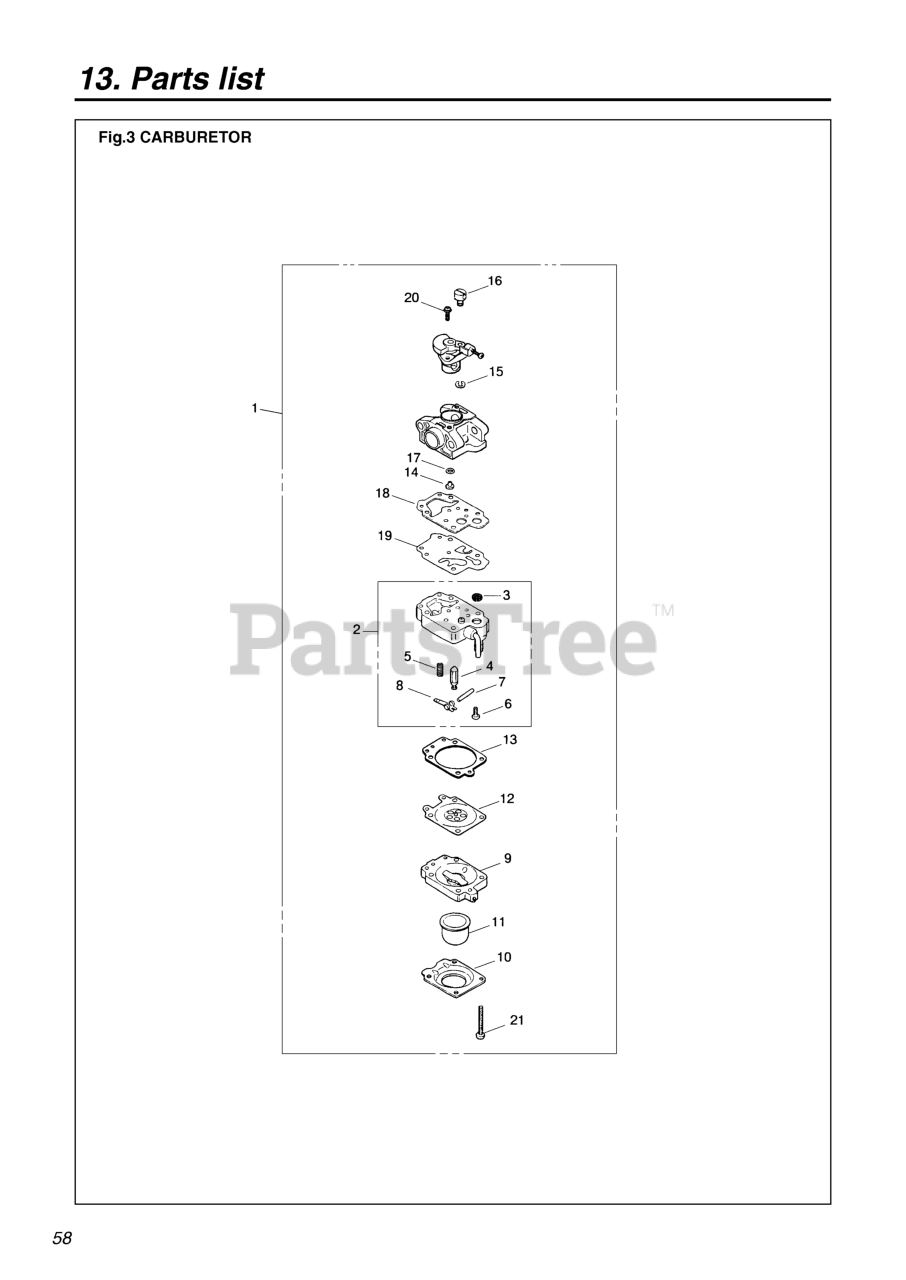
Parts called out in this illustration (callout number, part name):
1	CARBURETOR ASSY
2	BODY, PUMP
4	VALVE, INLET
6	SCREW, METERING LEVER PIN
7	PIN, METERING LEVER
8	LEVER
9	BODY, PURGE
10	COVER, PUMP
11	PUMP, PRIMING
12	DIAPHRAGM (RPLS 3310-81260)
13	GASKET, DIAPHRAGM
14	JET
15	RING
16	SWIVEL
17	RING, O
18	GASKET, PUMP
19	DIAPHRAGM
21	SCREW
